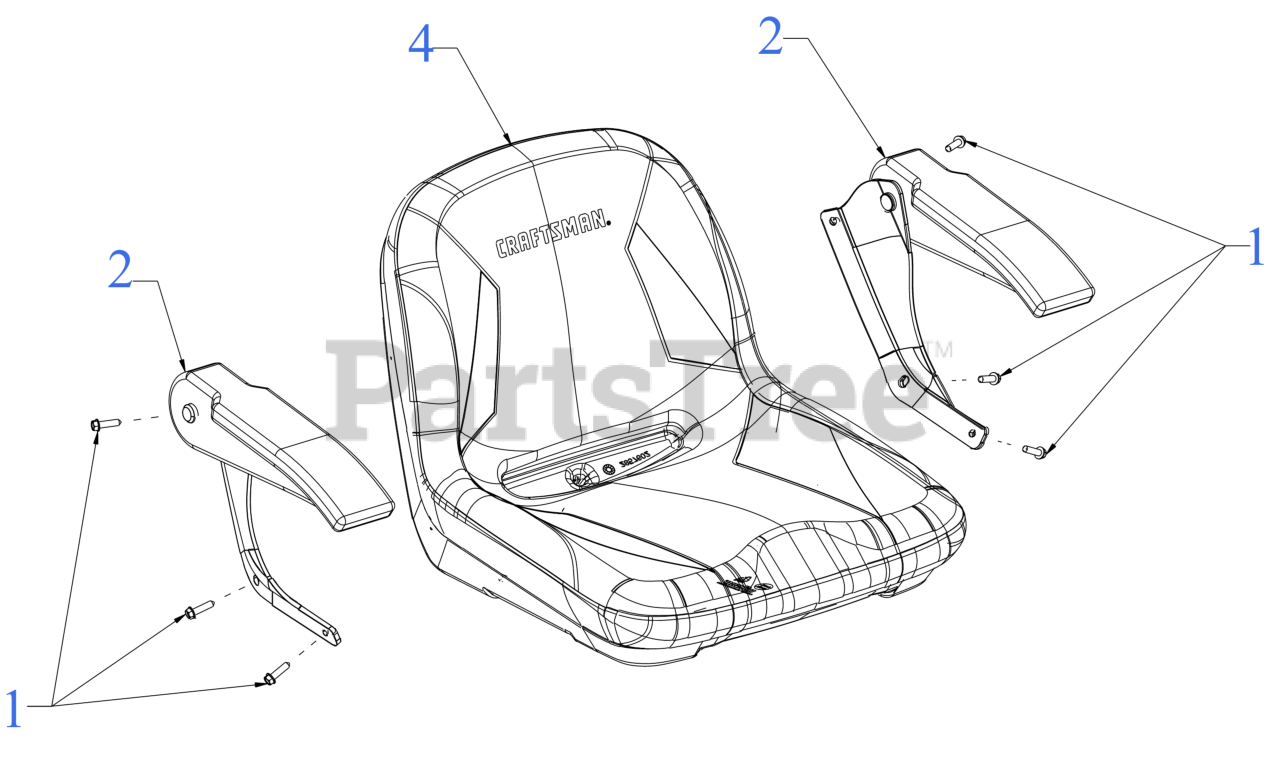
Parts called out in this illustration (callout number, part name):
1	SCREW 1/4-14X 1.00
2	LH & RH ARMREST KIT
4	SEAT (HI/CRFTMN CUT/SEW)
4	SEAT SWITCH N/C,N/C
4	RETAINING CLIP
